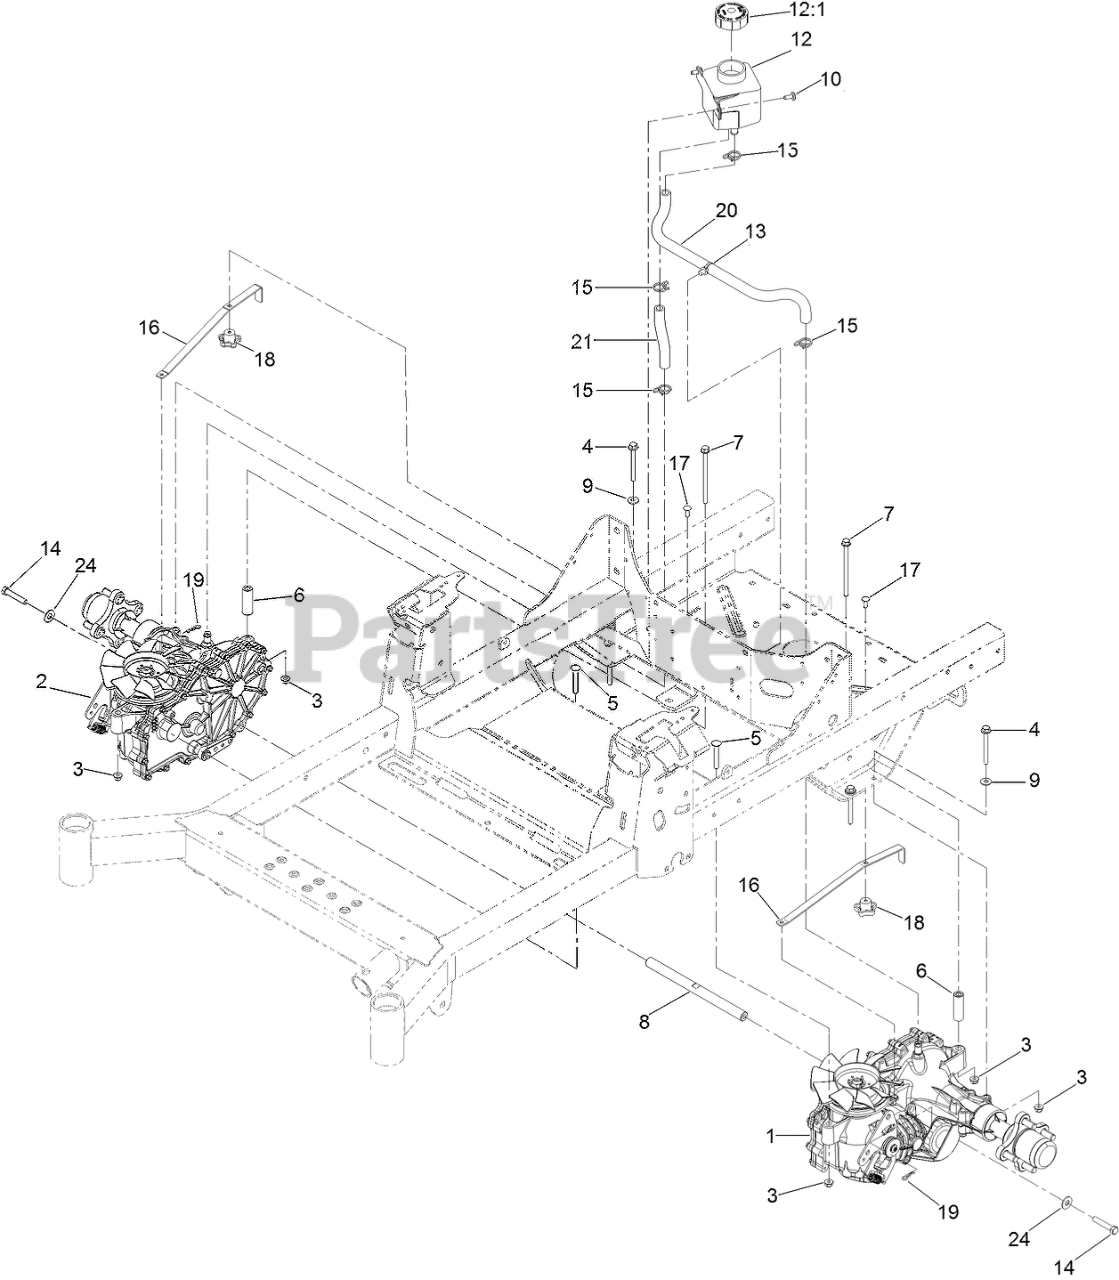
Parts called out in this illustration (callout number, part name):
1	TRANSAXLE ASM LH
2	TRANSAXLE ASM RH
3	NUT-HF, NI
4	SCREW-HHF
5	BOLT-CARR
6	SPACER-HYDRO
7	SCREW HHF
8	SHAFT-SPACER
9	WASHER-SPRING
10	SCREW-TORX
12	TANK-HYD
12:1	CAP-RESERVOIR, HYD
13	CLIP-TIE
14	SCREW-HH W/LOCTITE
15	CLAMP-HOSE
16	ARM-BYPASS, HYDRO
17	BOLT-CARR
18	KNOB-HANDLE
19	PIN-COTTER
20	HOSE-HYDRAULIC
21	HOSE-HYDRAULIC
24	WASHER-FLAT
